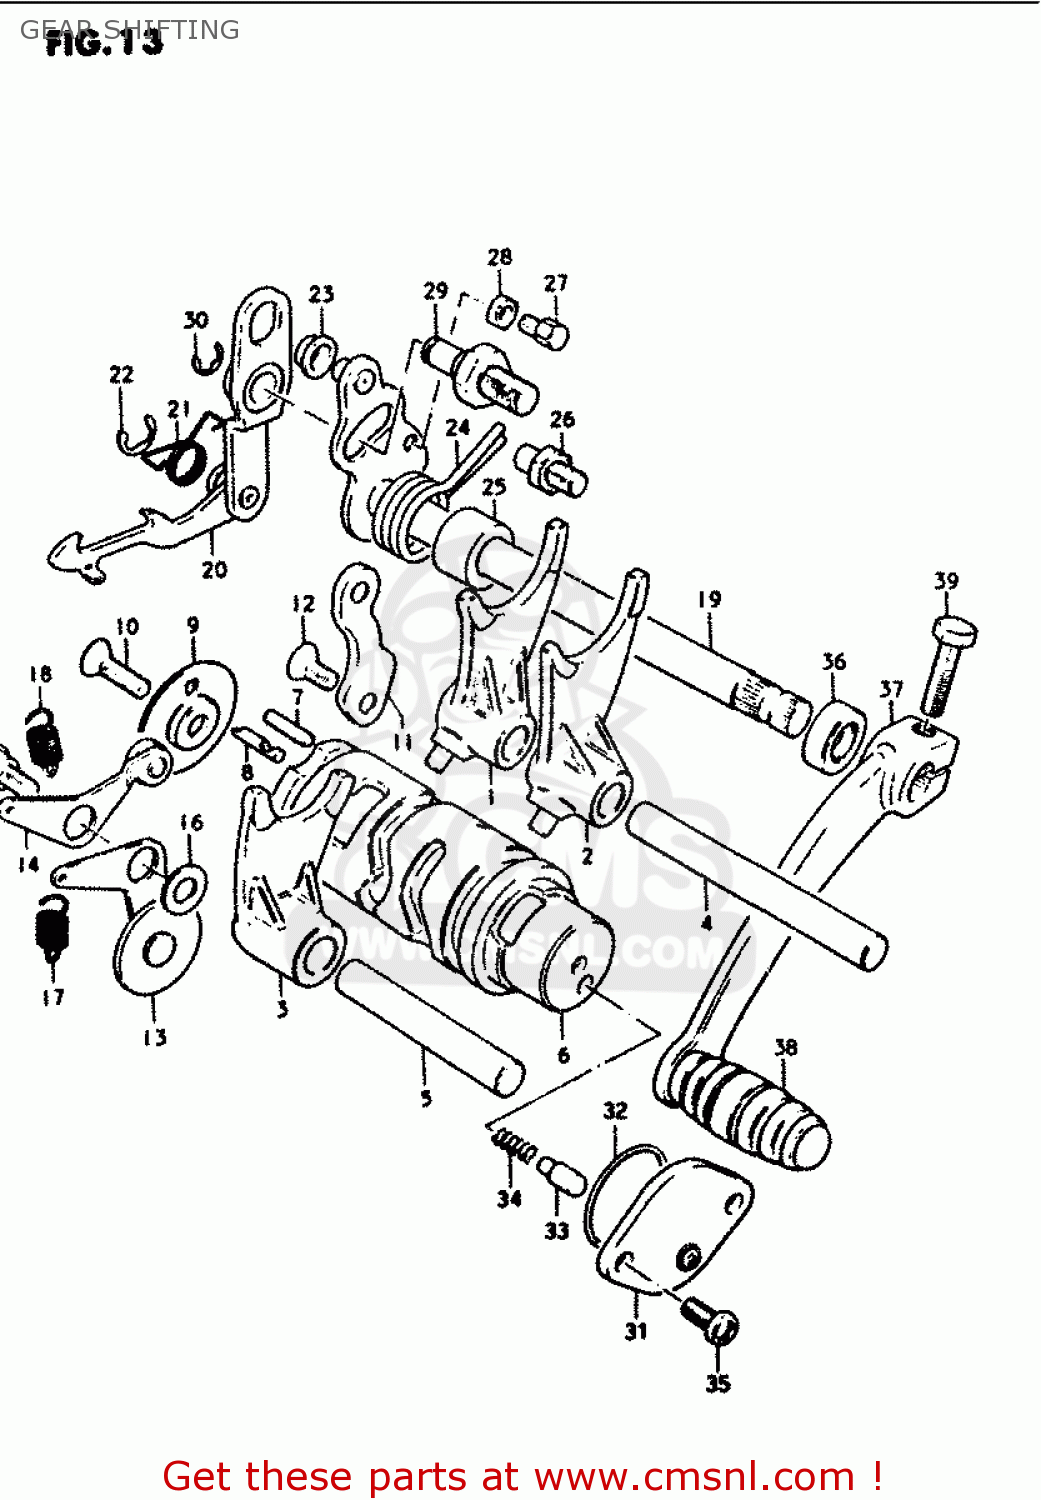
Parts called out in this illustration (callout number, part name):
1	FORK,GEAR SHIFT NO.1
2	FORK,GEAR SHIFT NO.2
3	FORK,GEAR SHIFT NO.2
4	SHAFT,GEAR SHIFT FORK
5	SHAFT,GEAR SHIFT FORK
6	CAM,GEAR SHIFT
7	PIN(4X15.8)
8	PIN
9	RETAINER,GEAR SHIFT CAM DR PIN
10	SCREW
11	GUIDE,GEAR SHIFT CAM
12	SCREW
13	STOPPER,GEAR SHIFT CAM
14	STOPPER,GEAR SHIFT CAM NEUTRAL
15	BOLT(6X18.3)
16	WASHER
17	SPRING
18	SPRING
19	SHAFT,GEAR SHIFT
20	PAWL,GEAR SHIFT
21	SPRING
22	E RING
23	SPACER(7X10X5)
24	SPRING
25	SPACER(12X20X15.3)
26	STOPPER,GEAR SHIFT CAM
27	BOLT,GEAR SHAFT RETURN SPR SET
28	NUT
29	STOPPER,GEAR SHIFT CAM
30	E RING 6MM
31	BODY,GEAR SHIFT SWITCH
32	O-RING (D:2.4 ID:26.2)
33	PIN(5X15.5)
34	SPRING
35	SCREW
36	OIL SEAL
37	LEVER ASSY,GEAR SHIFT
38	RUBBER,GEAR SHIFT PEDAL
39	BOLT
